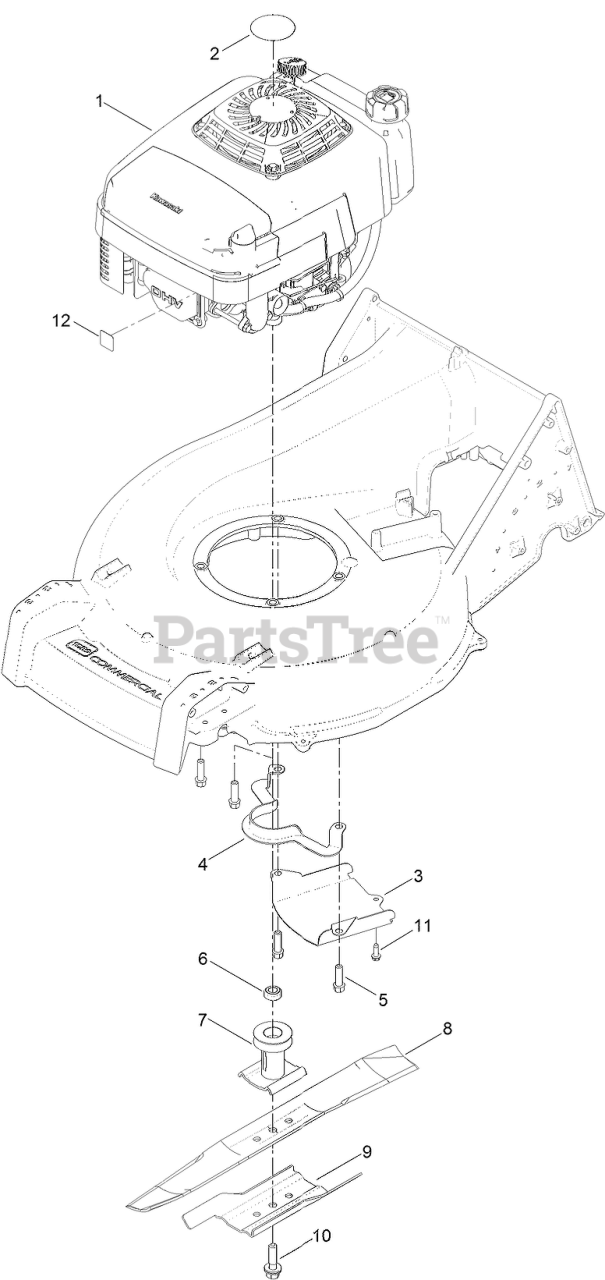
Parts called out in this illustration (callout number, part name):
3	SHIELD-GRASS
4	GUIDE-BELT
5	SCREW-TAPTITE
6	SPACER-DRIVER, BLADE
7	DRIVER-BLADE
8	BLADE-RECYCLING
9	ACCELERATOR-BLADE
10	BOLT-BLADE
11	SCREW-HWHTF
12	DECAL-PRIMER
